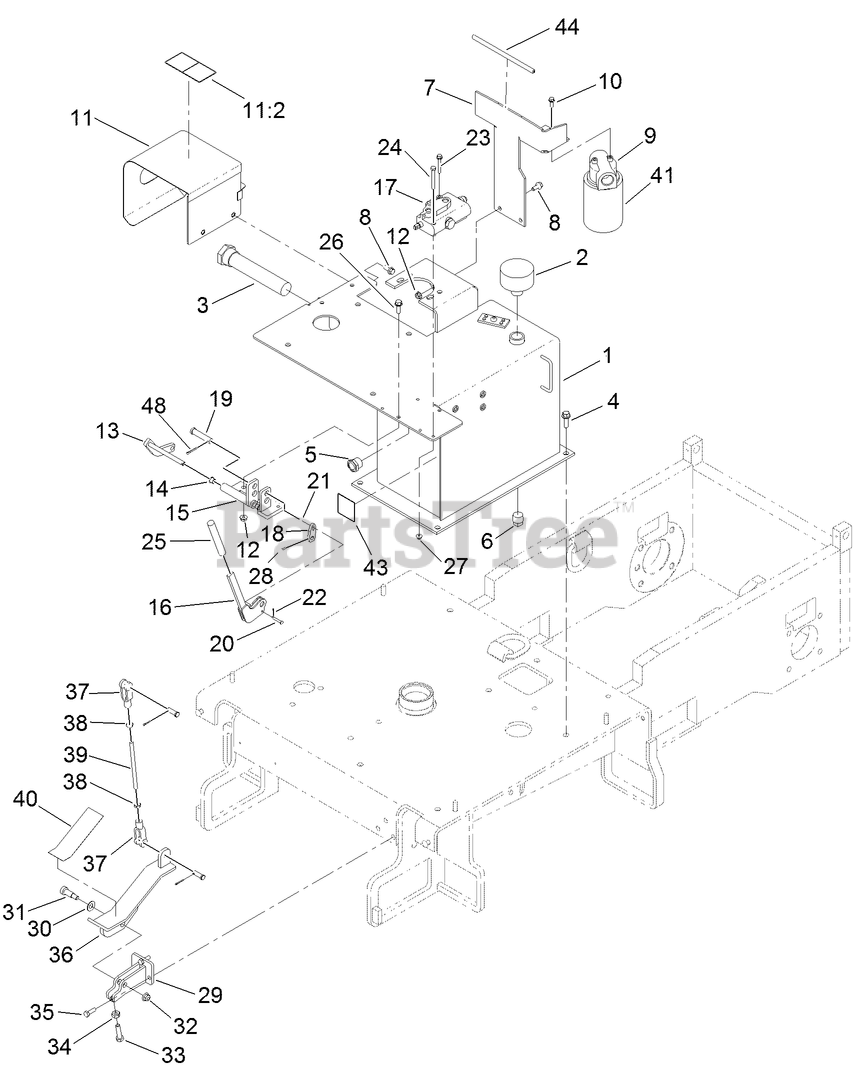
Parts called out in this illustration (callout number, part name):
1	TANK-HYDRAULIC
2	BREATHER-FILLER
3	STRAINER
4	SCREW-HHF
5	GLASS SIGHT ASM
7	BRACKET-FILTER, OIL
8	SCREW-HHF
9	FILTER-RETURN
10	SCREW-HHF
11	HEAT SHEILD ASM
11:2	DECAL-SURFACE, HOT
12	NUT-FLANGE
14	BEARING
15	GUIDE-SHAFT
16	LEVER-CONTROL, VALVE
17	DIRECTIONAL HYD VALVE ASM
18	PLATE-LEVER, FOOT CONTROL
19	PIN-CLEVIS
20	PIN-CLEVIS
21	WASHER
22	PIN-COTTER
23	SCREW-HHF
24	SCREW-HH
25	GRIP-HANDLE
26	SCREW-HHF
27	NUT-HF
29	MOUNT-PEDAL
30	WASHER-BELLEVILLE
31	SCREW-HSBH
32	NUT-HF, NI
33	SCREW-HH
35	SCREW-HH
36	PEDAL-DUMP
37	YOKE-LINKAGE, BRAKE
38	NUT-HJ
39	ROD-LINKAGE
40	TREAD-SKID
41	ELEMENT-HYD OIL, 10 MICRON
43	DECAL-P BRAKE
44	TRIM-FILTER BRACKET
48	PIN-COTTER
